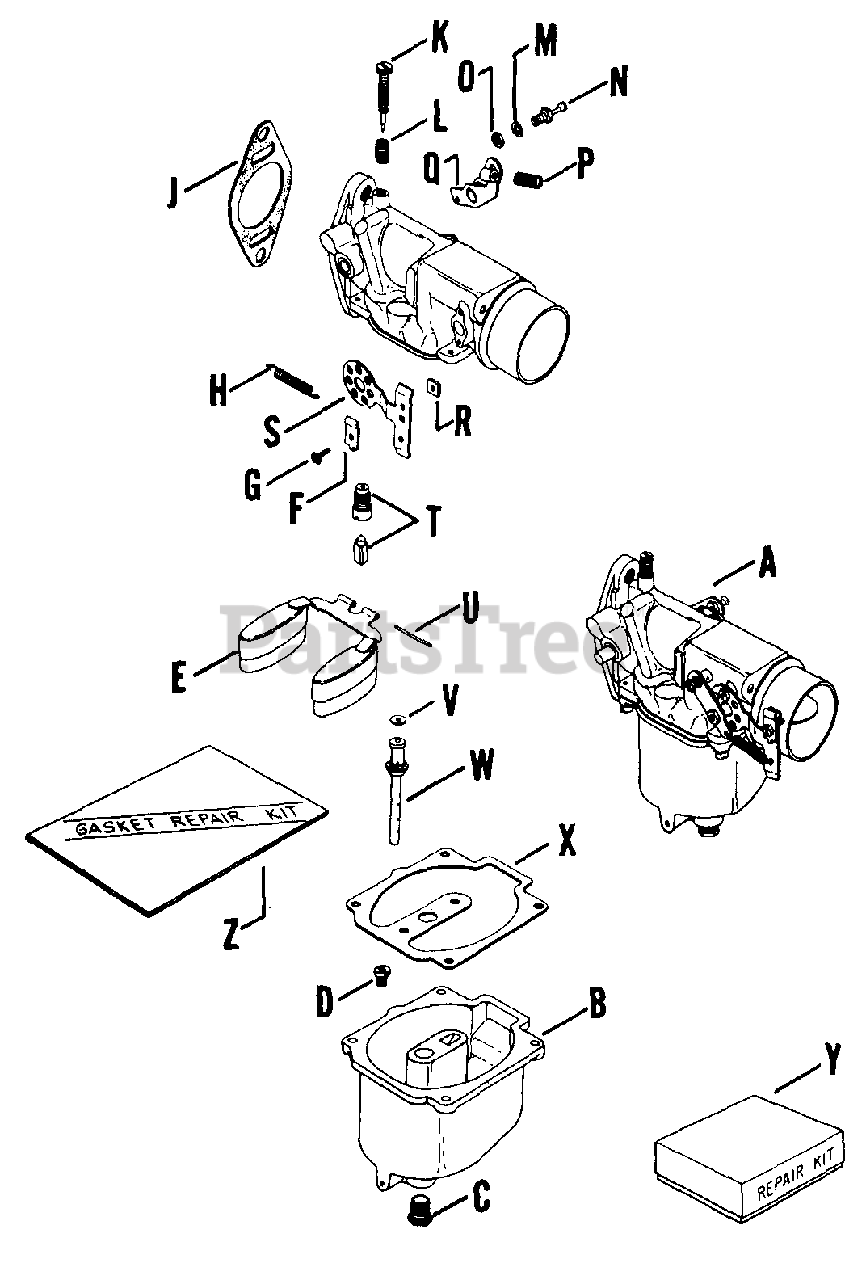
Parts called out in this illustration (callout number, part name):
B	BOWL - DISCONTINUED
C	PLUG, PIPE DISCONTINUED
H	SPRING - DISCONTINUED
K	NEEDLE - DISCONTINUED
L	SPRING - DISCONTINUED
Q	LEVER - DISCONTINUED
X	GASKET - DISCONTINUED
